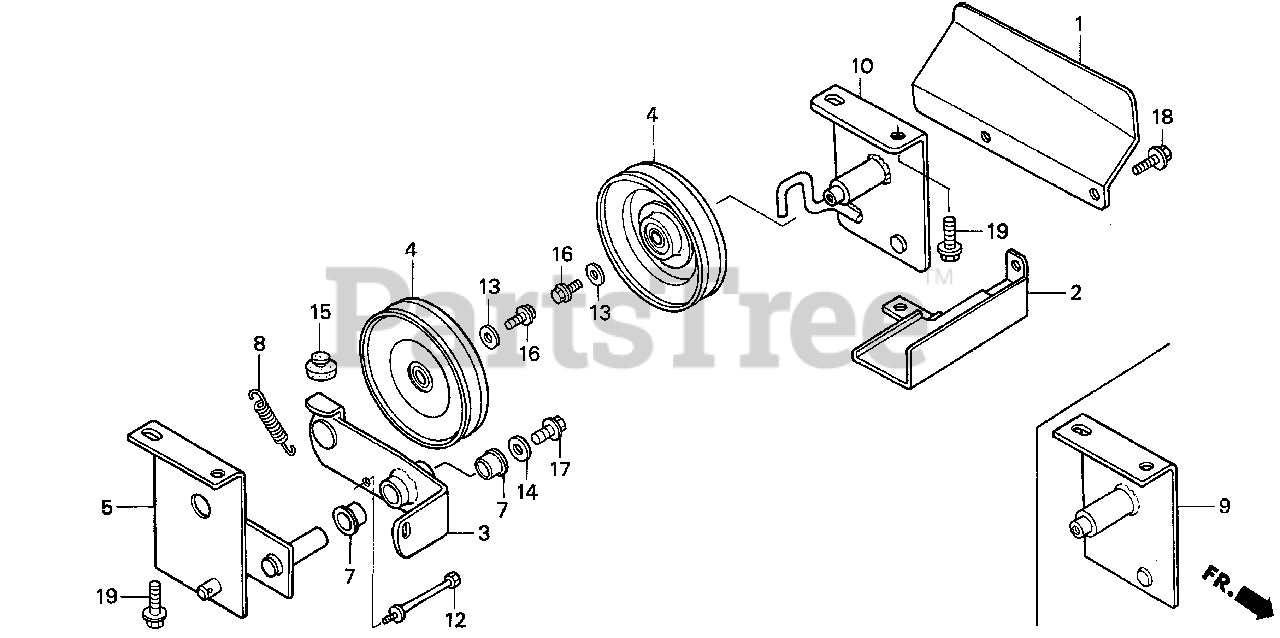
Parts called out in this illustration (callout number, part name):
1	COVER, FRAME (LOWER)
2	COVER, SIDE
3	ARM, TENSIONER
4	PULLEY, TENSIONER
5	BRACKET, R. ROLLER
7	BUSH (17X23X19)
8	SPRING, TENSIONER
9	BRACKET, L. ROLLER
10	BRACKET, L. ROLLER
12	BOLT, BELT STOPPER
13	WASHER (6MM)
14	WASHER, PLAIN (8MM)
15	RUBBER B, STAND STOPPER
16	BOLT, FLANGE (6X16)
17	BOLT, FLANGE (8X14)
18	BOLT, FLANGE (10X22)
19	BOLT, FLANGE (10X20)
